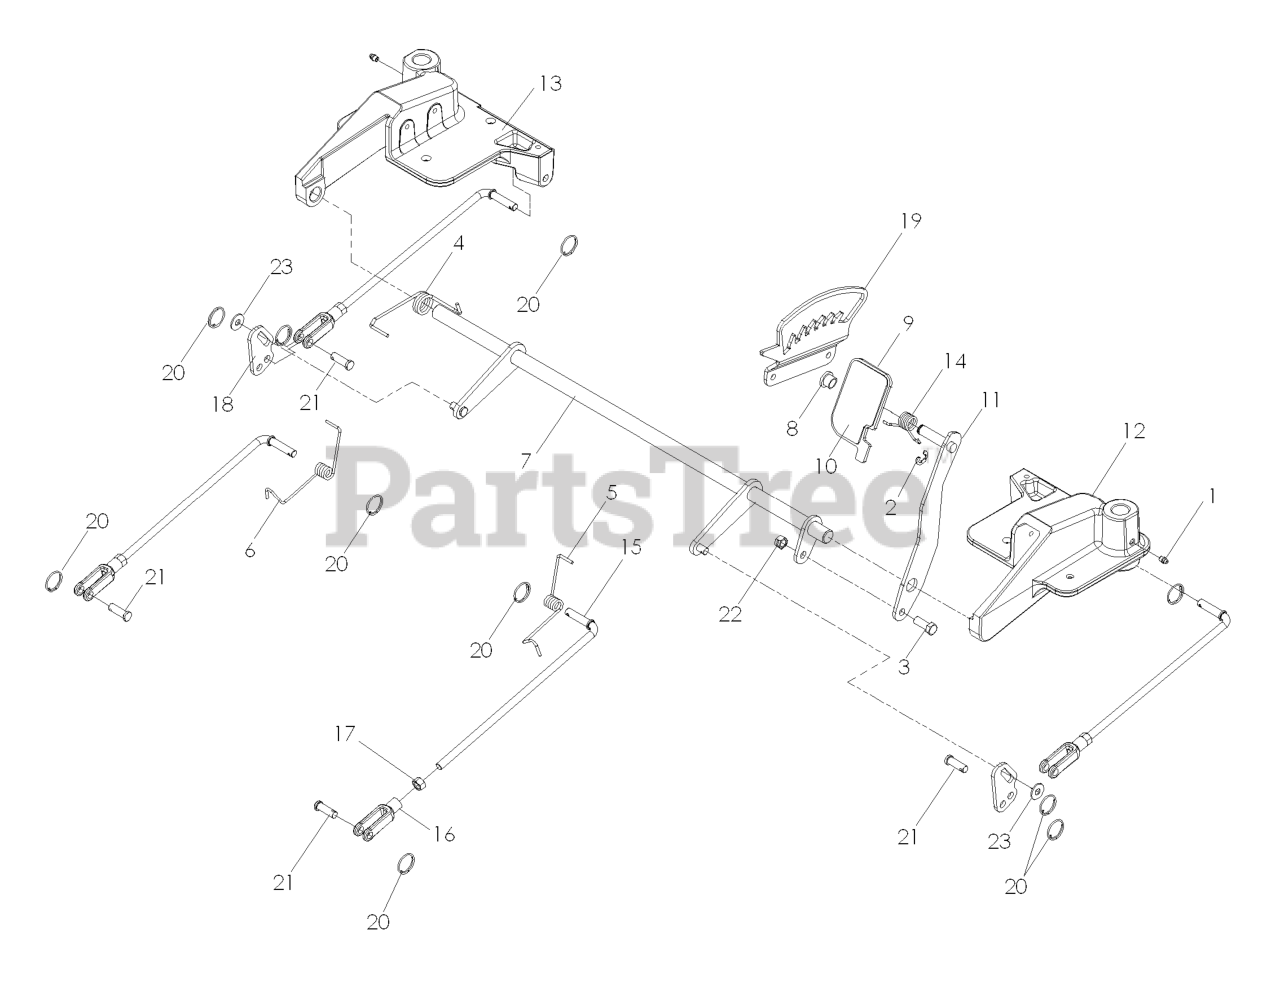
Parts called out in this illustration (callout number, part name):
1	ZERK
2	E-RING 1/2 (2 2)
3	HEX BOLT 3/8 X 1"
4	TORSION SPRING, DECK LIFT
5	SPRING, DECK ROD RIGHT
6	SPRING, DECK ROD LEFT
7	DECK LIFT ASM PAINTED
8	BUSHING, FLANGED NYLON
9	FOOT PEDAL
10	FOOT PAD, NON-SLIP
11	LIFT FOOT, LEVER WELDED
12	CASTER CASTING, RIGHT, PAINTED
13	CASTER CASTING LEFT, PAINTED
14	SPRING, PEDAL, LIFT
15	DECK LIFT ROD
16	YOKE-3/8-24 PLTD
18	CONNECTOR, DECK LIFT
19	HEIGHT PLATE, DECK
21	CLEVIS PIN 3/8 X 1 1/8
22	NUT 3/8C CENTERBLOCK
23	WASHER 5/16 FLAT
